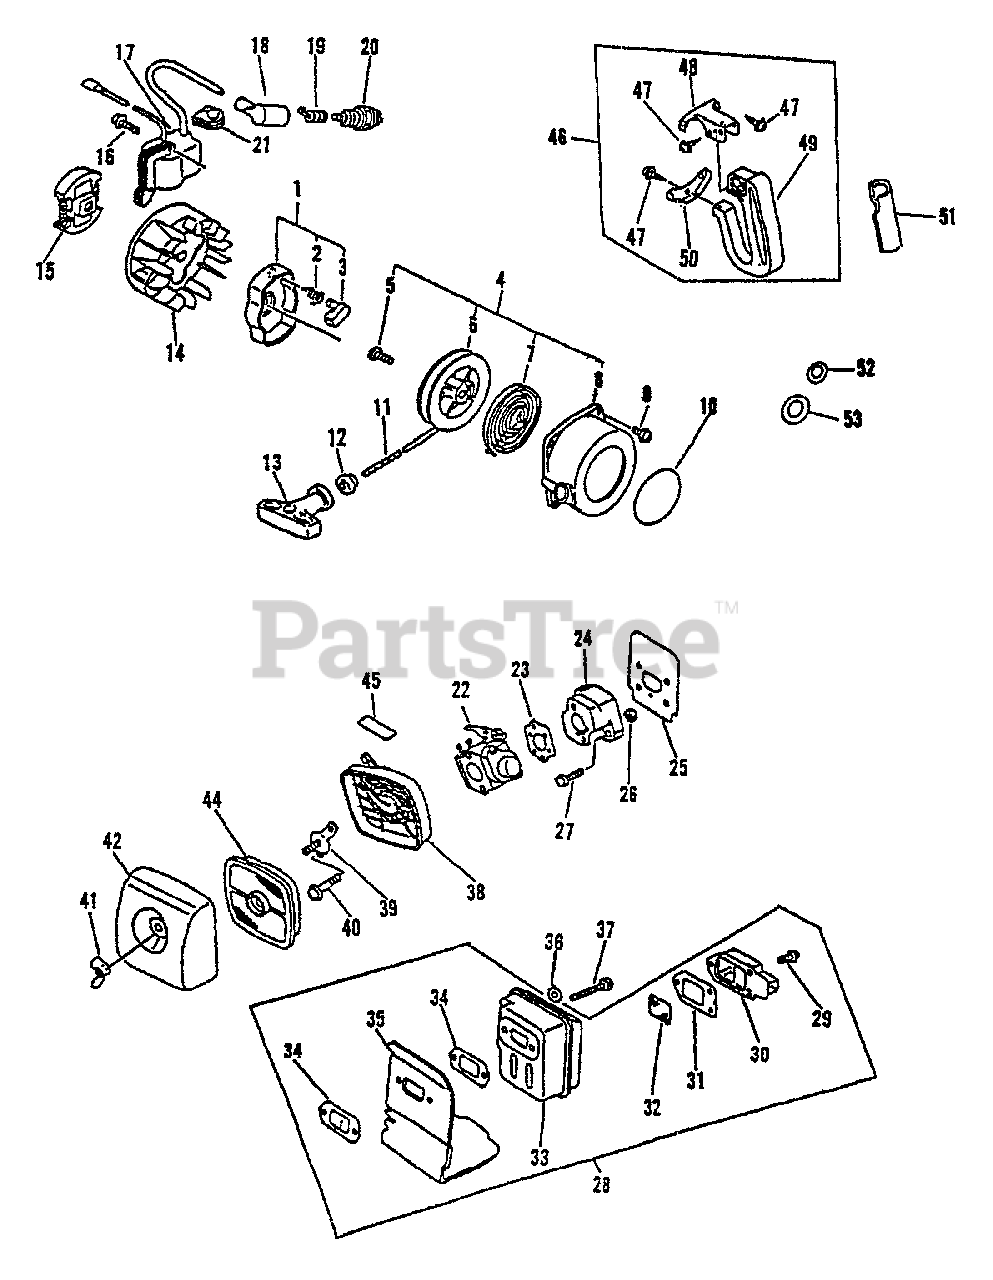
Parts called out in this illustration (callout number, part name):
1	PAWL ASSY, STARTER
2	SPRING, RETURN
3	PAWL, STARTER - BLACK
4	STARTER ASSY, RECOIL
5	SCREW
6	REEL, ROPE
7	SPRING, RECOIL
8	CASE, RECOIL STARTER
9	SCREW 4×22
10	LABEL, ECHO
12	GUIDE, ROPE
13	GRIP, STARTER
14	FLYWHEEL
15	CLUTCH ASSY
16	SCREW 4×22
17	COIL, IGNITION
18	CAP, SPARK PLUG
19	TERMINAL, SPARK PLUG
20	SPARK PLUG - BPM7A
22	CARBURETOR - C1U-K16
23	GASKET, INTAKE
24	INSULATOR, INTAKE
25	HEAT SHIELD, INTAKE
26	NUT M5
27	SCREW 5×20
28	MUFFLER ASSY
29	SCREW 4×10
30	GUIDE, EXHAUST - INNER
31	GASKET, EXHAUST
32	SCREEN, SPARK ARRESTER
33	MUFFLER
34	GASKET, EXHAUST
35	COVER, EXHAUST
36	WASHER, FLAT 5.5×10×0.8
37	BOLT 5×55
38	AIR FILTER CASE ASSY
39	PLATE, PREVENT
40	SCREW 5×65
41	WINGNUT - 6
42	COVER, AIR FILTER
44	FILTER, AIR - SINGLE LAYER
45	LABEL, CHOKE
46	HANDLE ASSY, SIDE
47	SCREW 5×14
48	BRACKET, HANDLE
49	HANDLE ASSY, SIDE
50	BRACKET, LOWER HANDLE
51	GRIP, HANDLE
